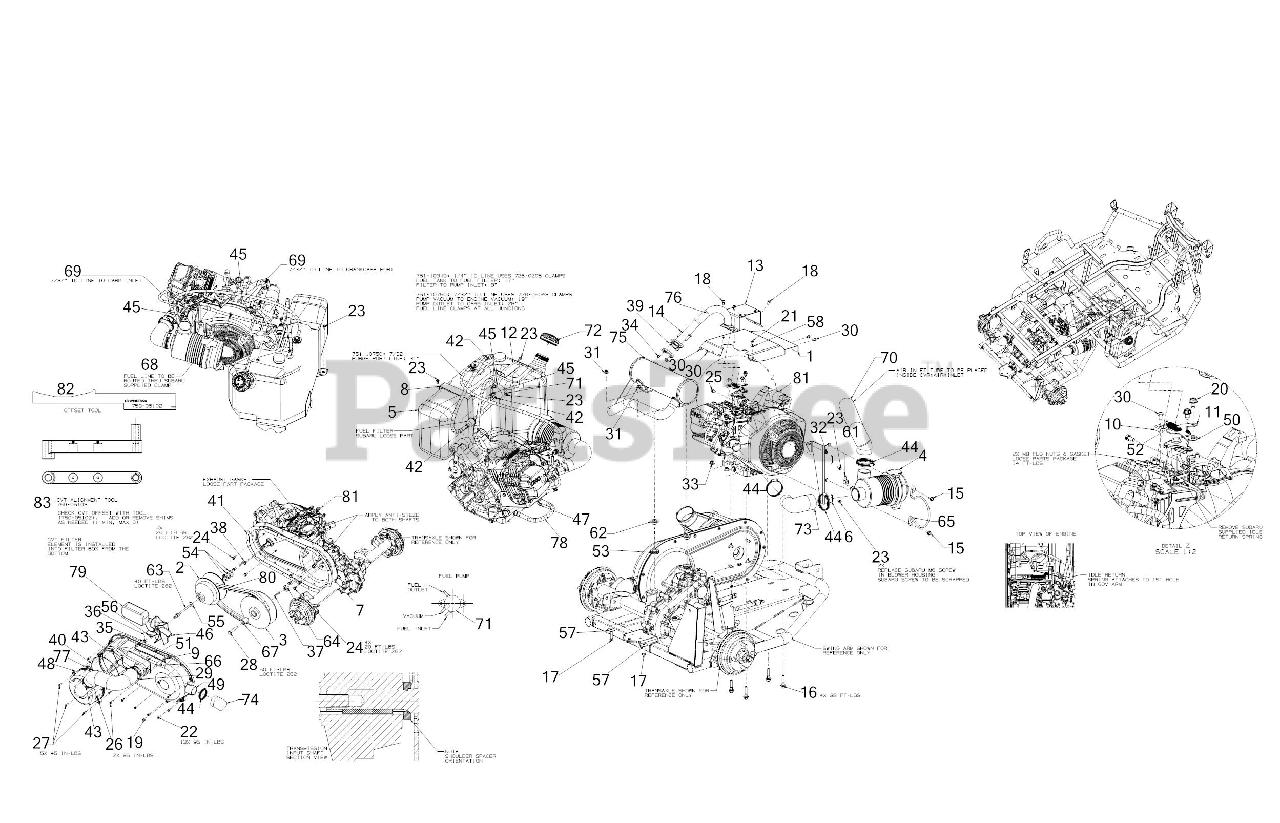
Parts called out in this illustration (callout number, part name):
1	ENGINE COVER ASSEMBLY
2	CVT DRIVER CLUTCH ASSEMBLY
3	CVT DRIVEN CLUTCH ASSEMBLY
4	AIRCLEANER FILTER ASSEMBLY
5	FUEL TANK ASSEMBLY
6	AIR FILTER MOUNTING BRACKET
7	BACK COVER PLATE
8	FUEL TANK STRAP BRACKET
9	CVT INTAKE TUBE SUPPORT
10	SPRING RETENSION BRACKET
11	THROTTLE MOUNTING BRACKET
12	FUEL TANK TOP BRACKET
13	AIR INLET COVER
14	SCREW 5/16-18 x 1.0 GR5
15	SCREW 5/16-18 x .750
16	SCREW 3/8-18 x 1.75 GR5
17	SCREW 5/16-18 x 1.25 GR5
18	SCREW 1/4-20 X.500
19	SCREW 5/16-18 x .625
20	SCREW 5/16-18 x .500
21	SCREW M5-.8X10MM SLOT/TORX
22	SCREW-TT 1/4-20 x .875
23	SCREW M6-1 x .625
24	HEX FLANGE BOLT 5/16-24:0.75
25	SCREW 1/4-20 x .620 GR5
26	SCREW 1/4-20 x 1.00
27	SCREW 1/4-15 x .750
28	SCREW 1/2-20 x 2.75 GR8
29	SCREW 1/4-20 x 2.375
30	SCREW M6-1.0X10MM GR8.8
31	FLANGE LOCK NUT 5/16-18
32	FLANGE LOCK NUT
34	FLANGE NUT
36	COTTER PIN-3/32
37	SQUARE KEY 3/16 x 3/16 x 2
38	KEY 1/4 X 3/16
39	EXHAUST GASKET
40	O-RING 7.98 X 8.137 X 0.103
41	CVT COVER SEAL
42	HOSE CLAMP 1/20
43	HOSE CLAMP
44	HOSE CLAMP 2-3"
45	HOSE CLAMP 0.470
47	DRAIN HOSE CLIP
48	CVT FAN COVER
49	CVT COVER
50	CONTROL PANEL COVER
51	CVT FILTER HOUSING
52	EXTENSION SPRING
53	GROMMET .75 X 1.063 X .4375
54	FLAT WASHER
55	FLAT WASHER
56	FLAT WASHER .510 x 1.00 x .060
57	FLAT WASHER .322 ID x 1.25 x .060
58	WASHER .215 X .622 X .077
61	90 DEGREE FITTING
62	SHOULDER SPACER .750 x .145
63	THREADED FAN ROD
64	SHOULDER SPACER
65	AIR FILTER STRAP ROD
67	CVT DRIVEN SPACER
68	FUEL HOSE LOW PERMEATION
69	FUEL HOSE LO PERMEATION
70	AIR INLET HOSE
71	ENGINE FUEL PUMP
72	FUEL CAP W/TET
73	AIR FILTER INTAKE HOSE
74	CVT EXHAUST HOSE
76	EXHAUST PIPE
77	CVT INTAKE TUBE
78	OIL HOSE DRAIN
79	CVT INLET FILTER
80	CVT BELT 4X2
81	COMPLETE ENGINE
82	CVT OFFSET TOOL
83	CVT ALIGNMENT TOOL
